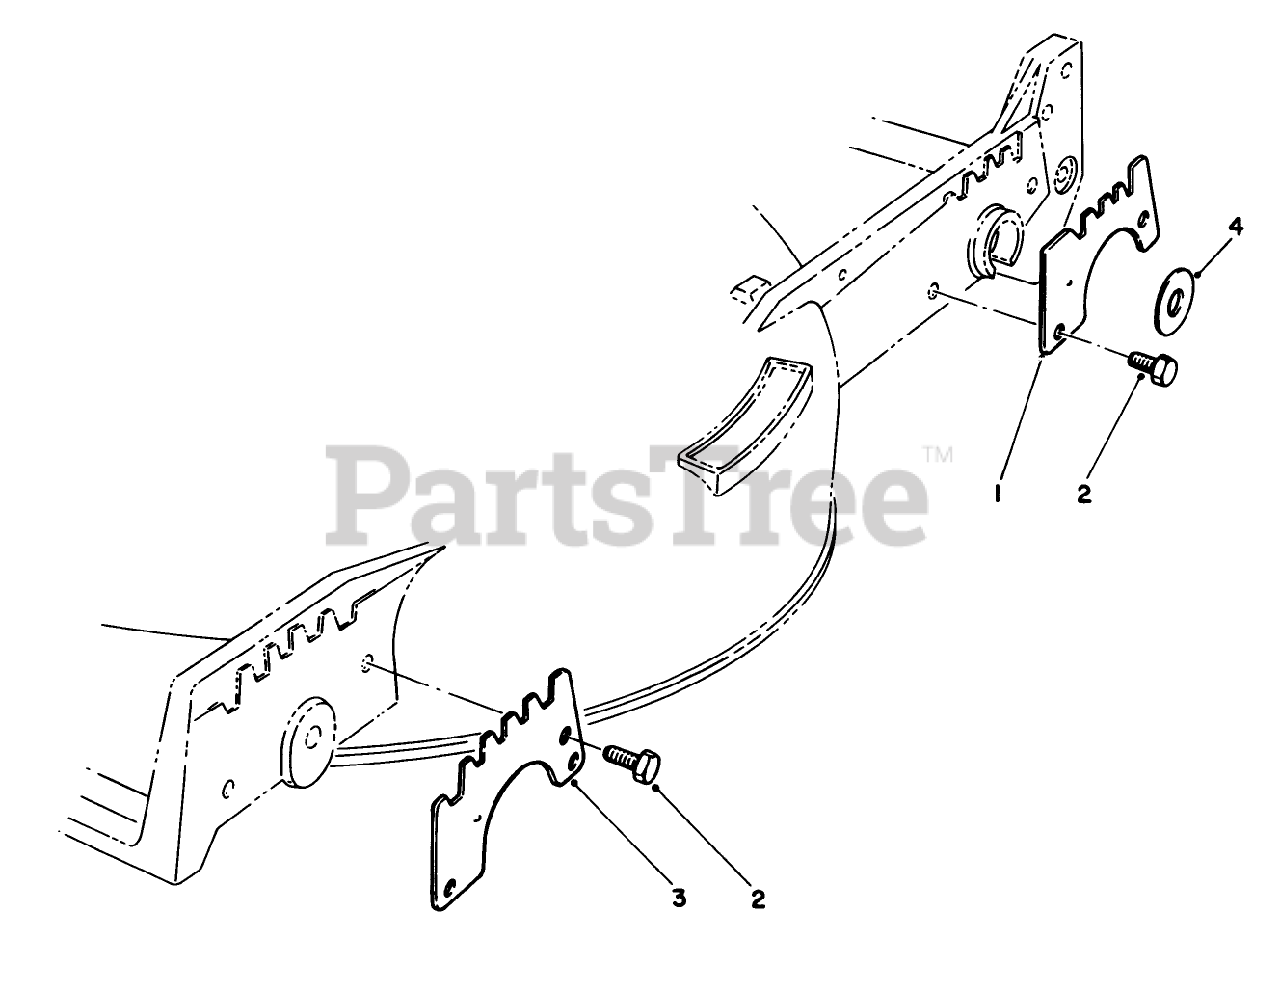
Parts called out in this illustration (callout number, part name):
1	WEAR PLATE,REAR
2	SCREW-HWH
3	WEAR PLATE
4	PIVOT WASHER
